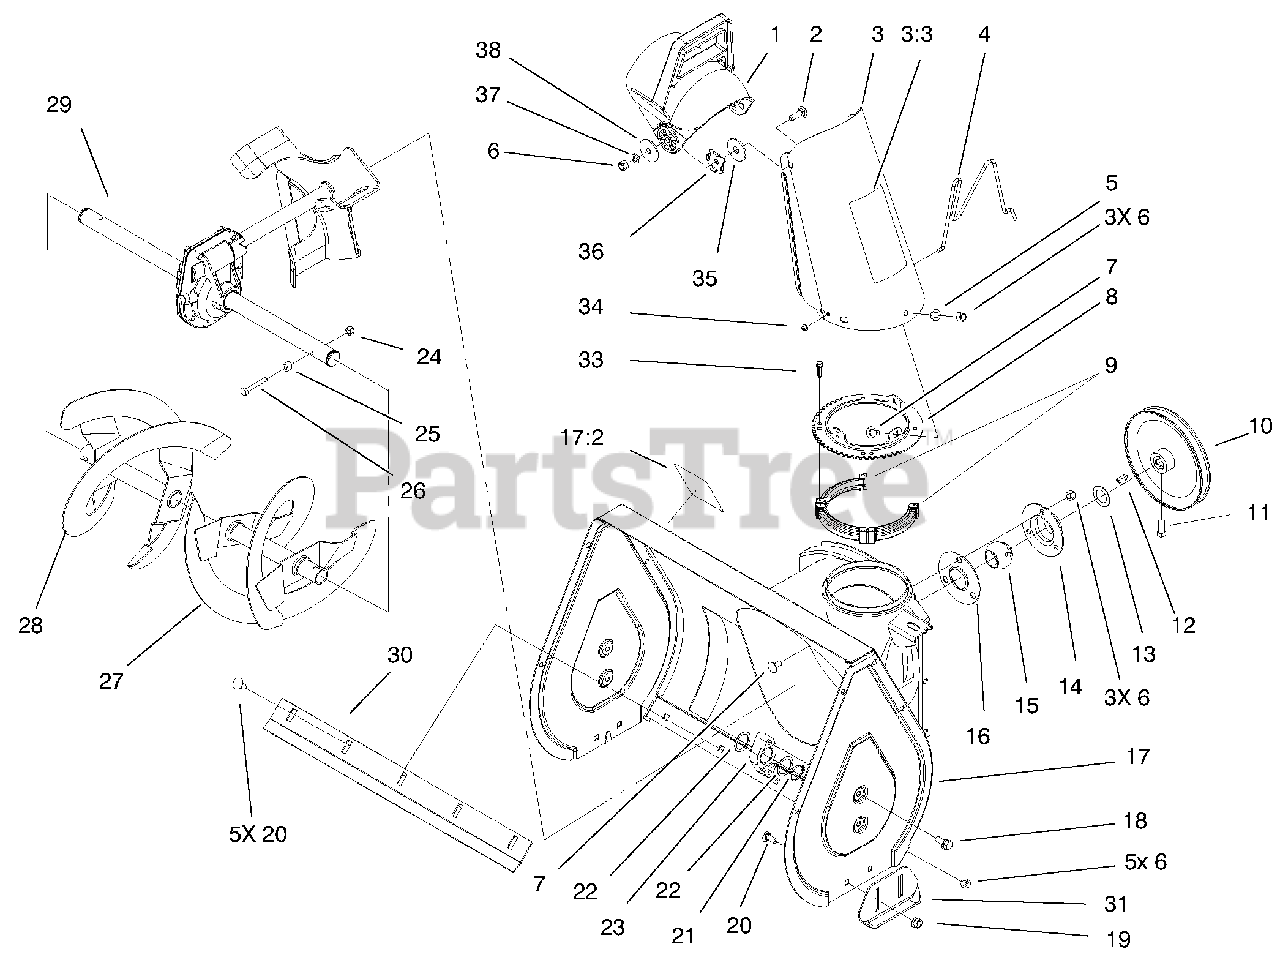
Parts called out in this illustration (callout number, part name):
1	Chute-Deflector
2	Screw-CARR
3	Chute ASM
3:3	Decal-Danger
4	Wire-Chute
5	Washer-Flat
6	Nut-Lock
7	Screw-CARR
8	Ring-Chute
9	Ring-Chute, Retainer
11	Screw-SQH Set
12	Key-Woodruff
14	Flange-Cup, Bearing
15	Bearing-Ball
16	Flange-Cup, Bearing
17	Auger Housing ASM
17:2	Decal-Warning, Auger
20	Screw-CARR
21	Ring-Retaining
23	Bearing-Auger
24	Nut-Lock
25	Spacer-Hub, Impeller
26	Screw-HH
29	22" Gear Case ASM
30	Blade-Scraper
33	Screw-Special
35	Washer-Rubber
36	Plate-Friction
37	Washer-Belleville
38	Washer-Flat
